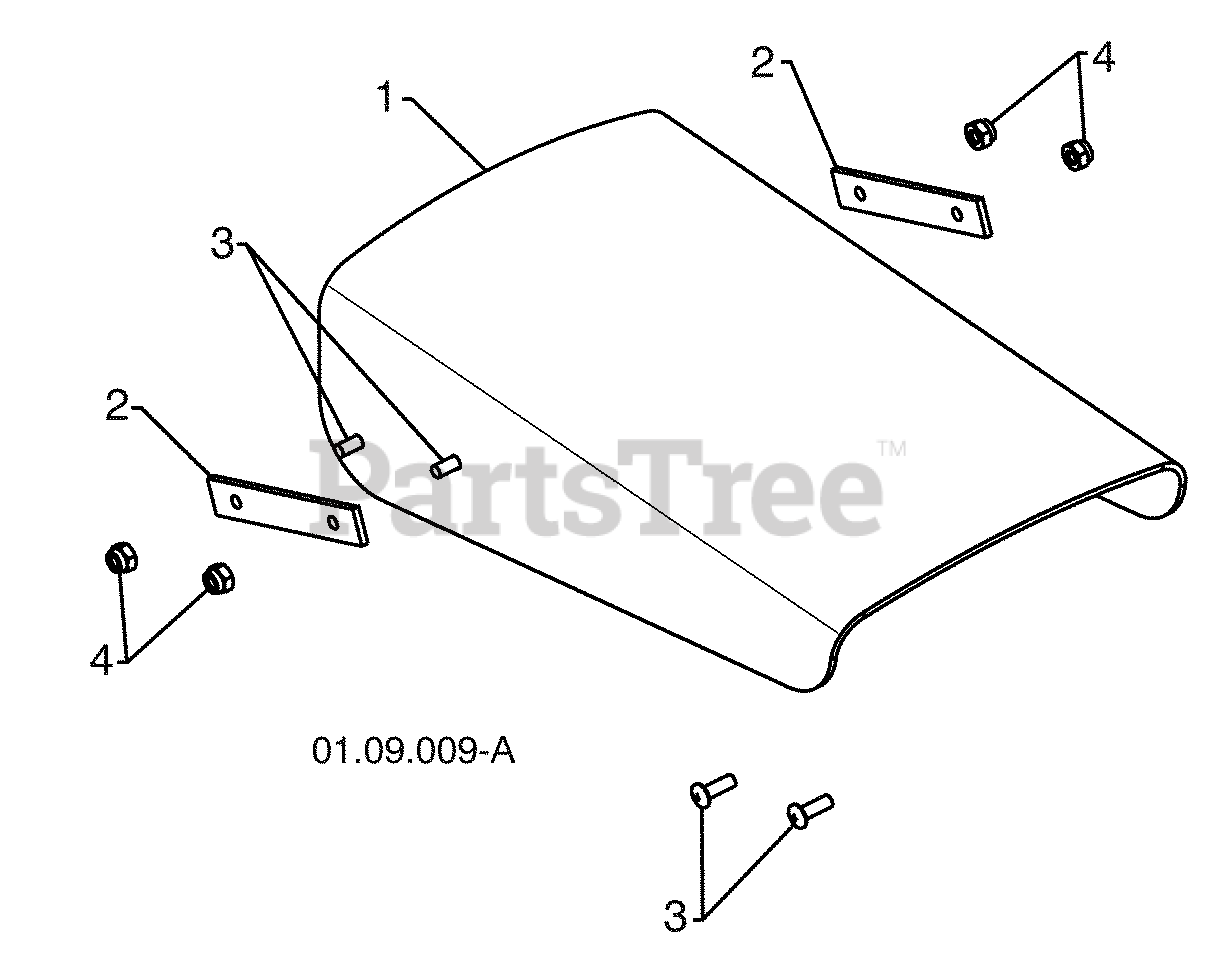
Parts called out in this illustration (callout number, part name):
1	SHIELD DEFLECTOR
2	STRAP
3	SCREW 8-32 X .50
